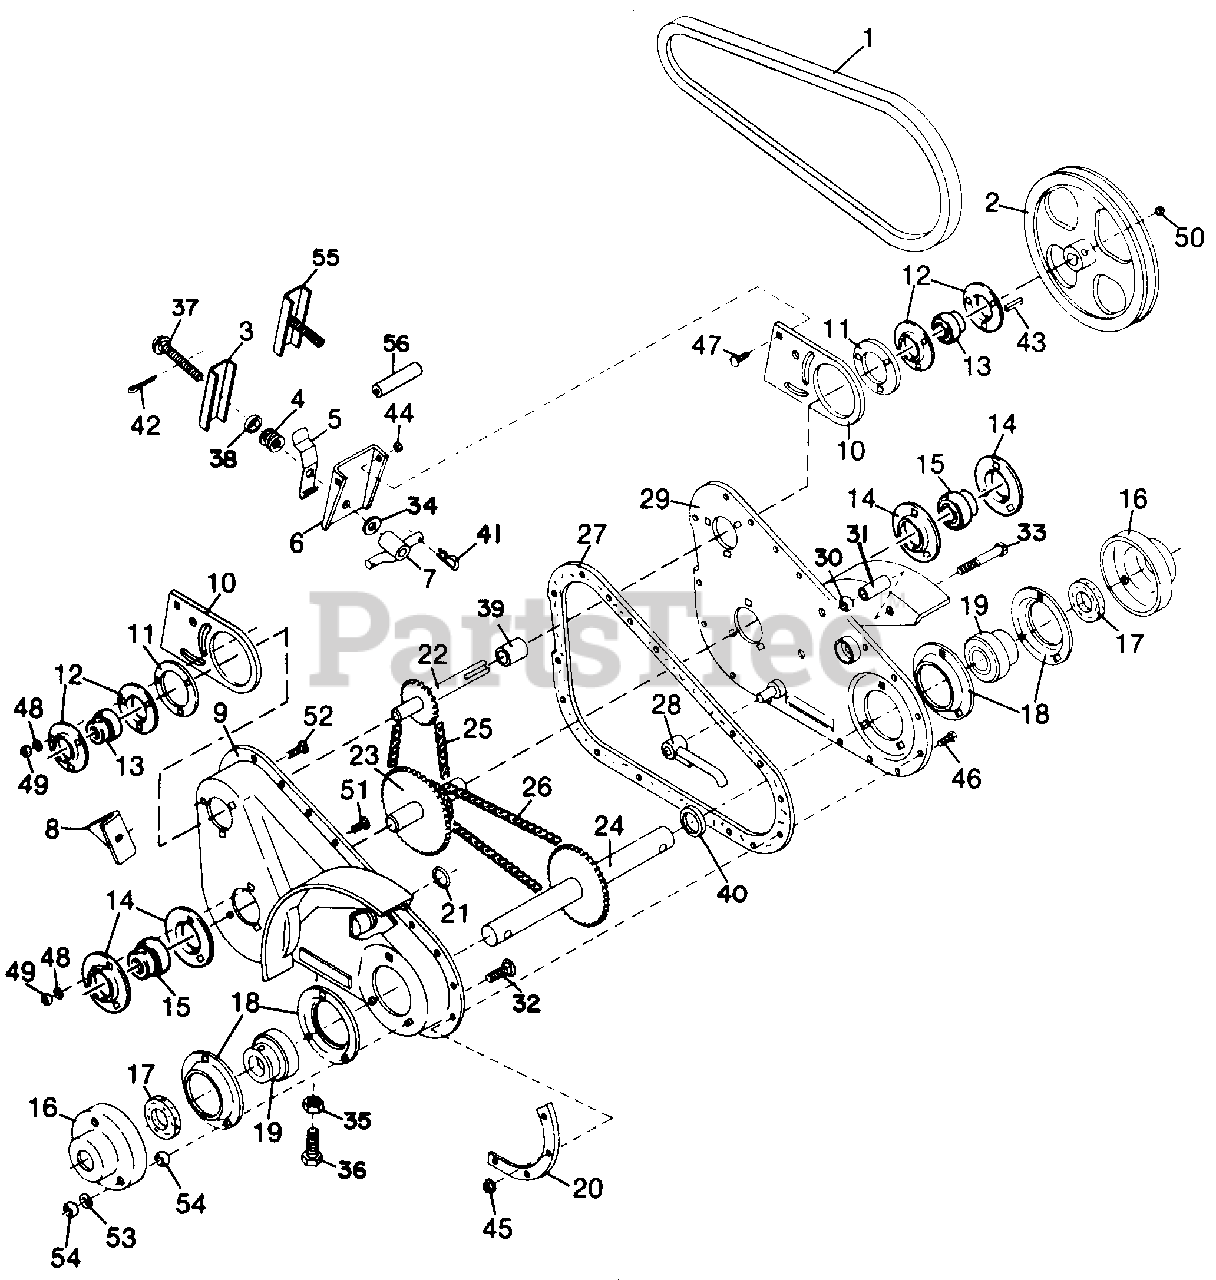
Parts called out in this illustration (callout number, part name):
1	Belt, Drive
2	Pulley, Drive
3	Handle, Adjustment -2B Tiller
4	Spring, Compression
5	Clip, Adjustment Stop -2B Tiller
6	Channel, Belt Tightener
7	Rod, Adjustment
8	Clip, Mounting Bracket
9	Housing, Chain Drive
10	Plate, Pivot
12	Flange, Bearing
13	Bearing w/o Locking Collar
14	Flange, Bearing
15	Bearing w/o Locking Collar
16	Excluder, Dust
17	Gasket, Felt Seal
18	Flange, Bearing
19	Bearing w/Locking Collar
20	Shoe, Formed
22	Shaft, Input
23	Sprocket, Idler -10 & 28 T
24	Shaft, Main Drive -18 T
25	Chain, Main
26	Chain, Tine Drive
27	Gasket, Chain Drive Housing
28	Adjustment, Chain
29	Plate, Housing Back
30	Nut, 3/8 Cad P/T Lock Type 8
31	Spacer, 3/8 X 3/4 X 1-3/4 -Mounting bracket
32	Bolt, 3/8 X 1-1/2 Crg Type 5
33	Bolt, 3/8 X 2-1/2 Phc Type 8
34	Washer, .531 X 1.062 X .074
35	Nut, 1/2 Pln Type 5
36	Bolt, 1/2 X 2 Pln Type 5
37	Bolt, Adjustment -2B Tiller
38	Spacer, 3/4 X 1 X 1/4 -2B Tiller
39	Spacer, 3/4 X 1-1/8 X 1-3/8 -2B Tiller- -Input shaft
41	Pin, Quick Attachable Cot
42	Pin, 5/32 X 1 Cot
43	Key, 3/16 X 1-5/8 Sq Parallel
44	Nut, 1/4 Cad P/T Lock Type 5
45	Nut, 1/4-28 X 3/4 Flange Lock
46	Bolt, 1/4-Nf X 3/4 Type 5
47	Bolt, 1/4 X 1 Crg Type 1
48	Washer, 5/16 Lock
49	Nut, 5/16 Type 5
50	Screw, 5/16 X 3/8 Pln C/Pt Hdl/Hs Set
51	Bolt, 5/16 X 3/4 Crg Type 5
52	Bolt, 5/16 X 1 Crg Type 1
53	Washer, 3/8 Lock
54	Nut, 3/8 Type 5
55	Tee, Belt Adjustment -2 Tiller
56	Spacer, 1/2 X 2-3/4 Pipe -2 Tiller
